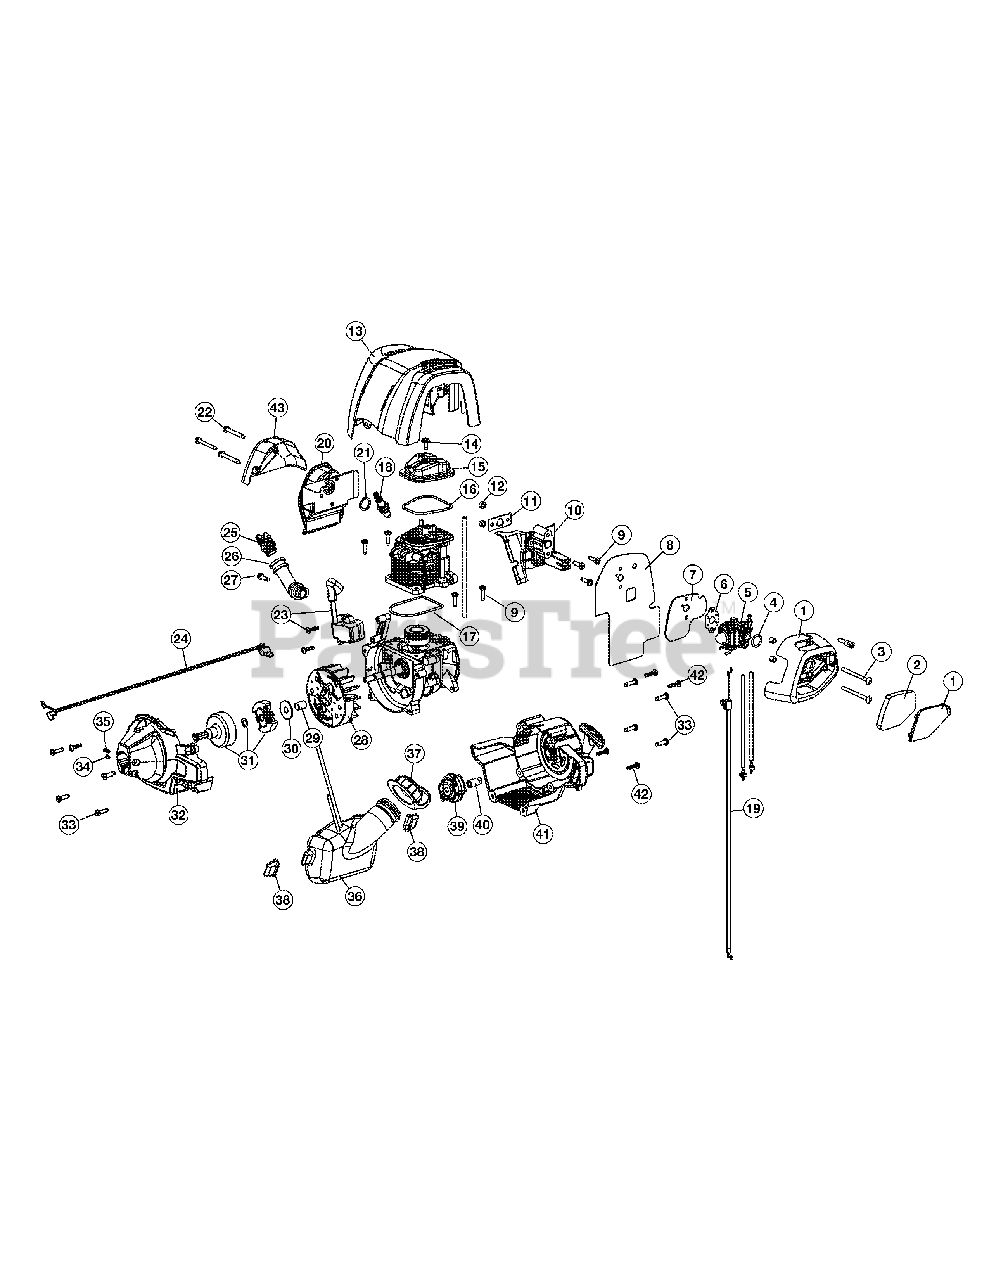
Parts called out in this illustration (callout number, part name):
1	Aircleaner Assembly
2	Air Filter
4	Carburetor O-Ring
5	Carburetor Assembly
6	Carburetor Gasket
7	Heat Sink
8	Carburetor Baffle
9	Screw
10	Insulator
11	Insulator Gasket
13	Engine Cover
15	Valve Cover
16	Valve O-Ring
17	Cylinder O-Ring
18	Spark Plug
19	Throttle Cable
20	Muffler Assembly
21	Muffler Gasket
22	Muffler Bolt
23	Module Assembly
24	Lead Wires
25	Oil Plug Assembly
26	Oil Fill Tube Assembly
28	Flywheel
29	Spacer
30	Clutch Washer
31	Clutch Assembly
32	Clutch Cover Assembly
34	Anti-rotation Screw
35	Clamp Screw & Nut
36	Fuel Tank
37	Fuel Cap
38	Fuel Tank Pad
39	Pawl Assembly
40	Electric Start Adapter
41	Starter Cover Assembly
43	Muffler Shield
